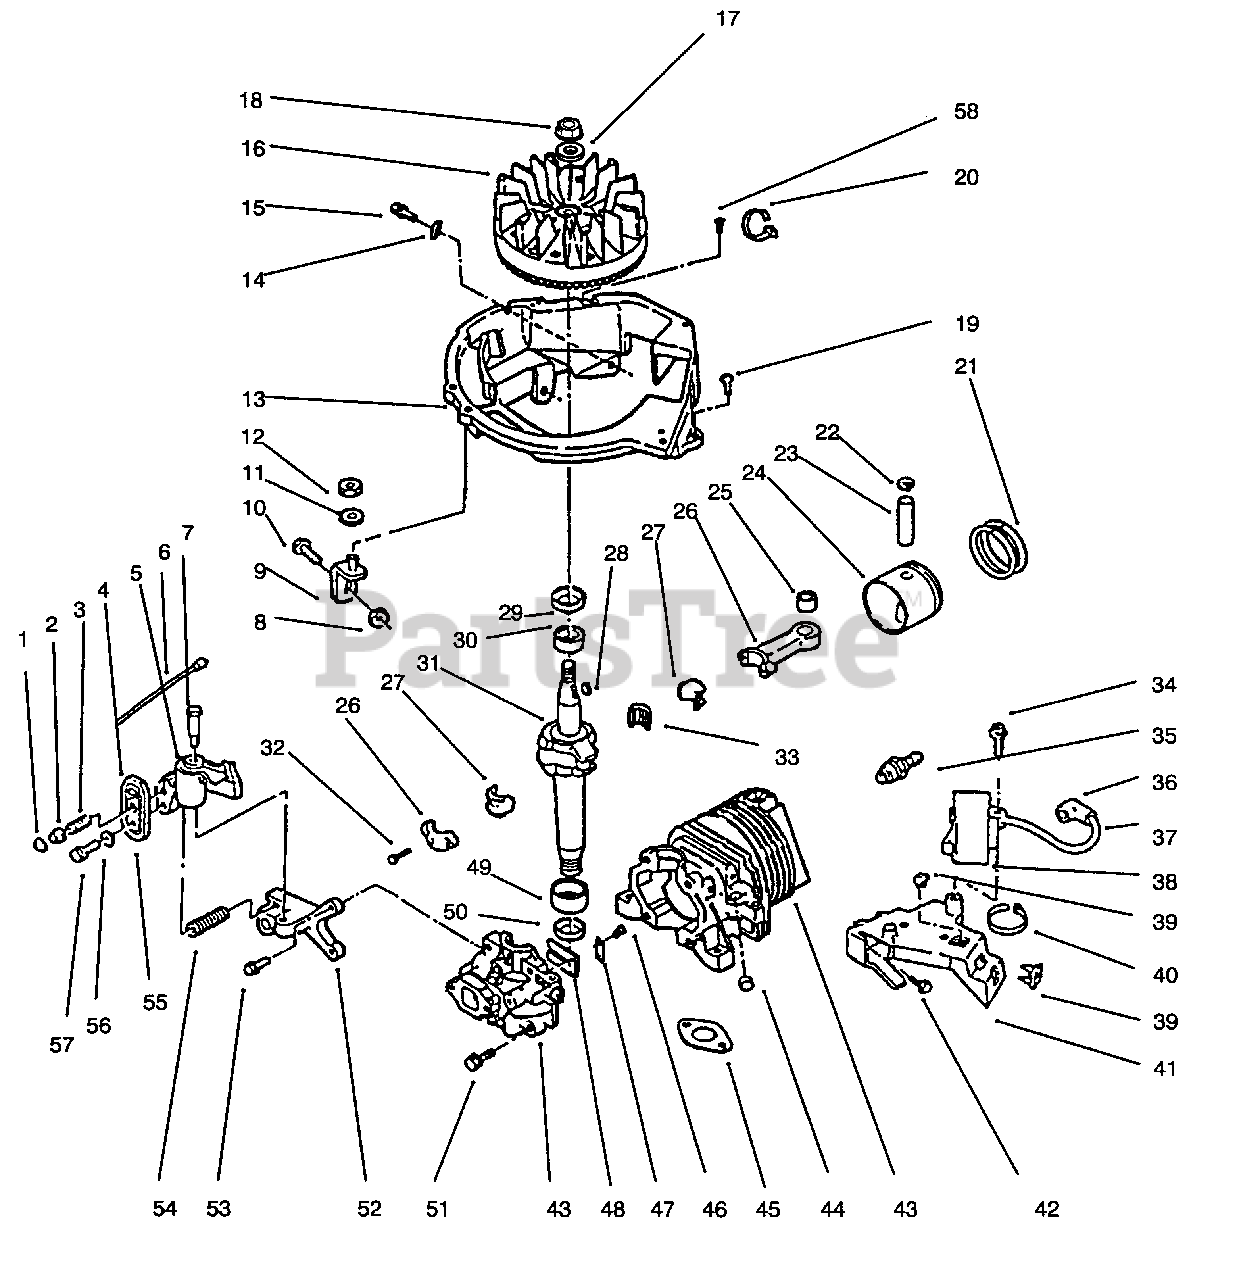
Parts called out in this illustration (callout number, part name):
1	Retainer
2	Actuator-Brake Lever
3	Spring-Cable, Return
4	Switch Assembly (Incl. Ref. #1,6,20, & 56-57)
5	Brake Assembly
6	Wire Lead
7	Bolt-Shoulder
9	Brace Assembly
11	Washer
13	Shroud-Base
14	"J"Clip
16	Flywheel Assembly
17	Washer-Lock
18	Nut-Flywheel
20	Tie Strap
21	Set-Ring
22	Ring-Retaining
23	Pin-Wrist
24	Piston & Connecting RodAssembly (Incl. Ref. #21-23, 25-27 & 32-33)
25	Bearing Assembly
26	Connecting Rod Assembly(Incl. Ref. #25,27,32 & 33)
27	Liner-Split
28	Key-Flywheel
29	Seal-Oil
30	Bearing-Main
31	Crankshaft
33	Set-Needle Bearing
34	Screw
35	Spark Plug
36	Cover-Terminal
37	Wire Lead
38	C. D. Ignition Module (Incl. Ref. #36, 37)
39	Grommet
40	Tie Strap
41	Bracket-C.D.
43	Cylinder & Crankcase Cover Assembly (Incl. Ref. # 46-48,51 & 53)
45	Gasket-Exhaust
47	Plate-Reed
49	Bearing-Main
50	Seal-Oil
52	Bracket-Brake
54	Spring-Brake
55	Case Assembly
56	Washer
57	Screw
